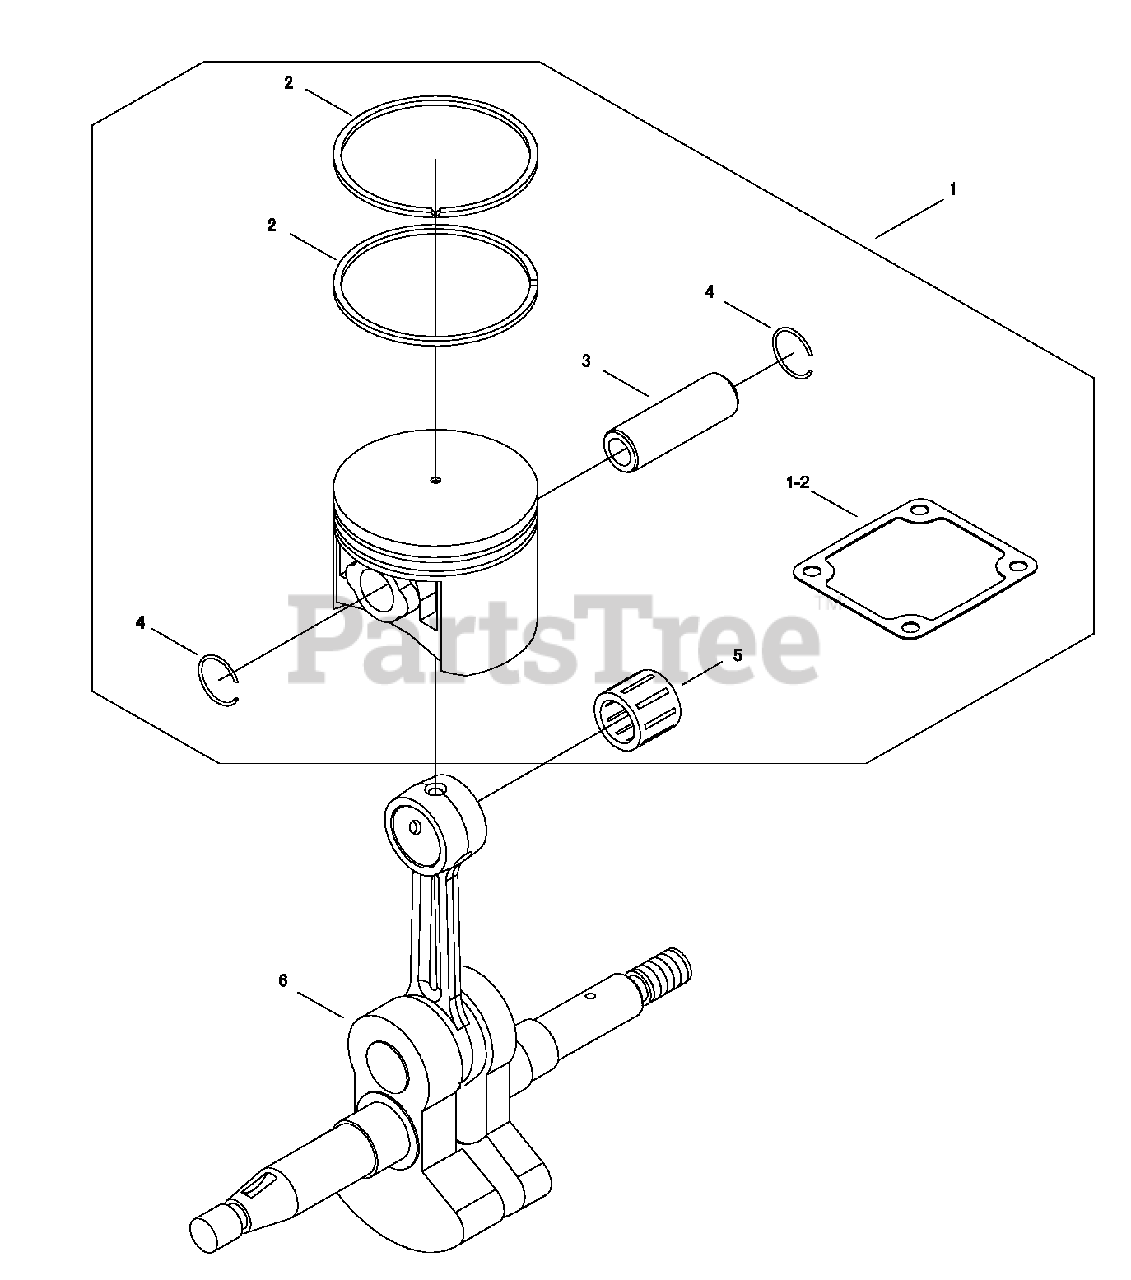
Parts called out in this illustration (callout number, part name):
1	PISTON SET
2	RING, PISTON
3	PIN, PISTON
4	RING, RETAINING
5	BEARING, NEEDLE
6	CRANKSHAFT ASSY
